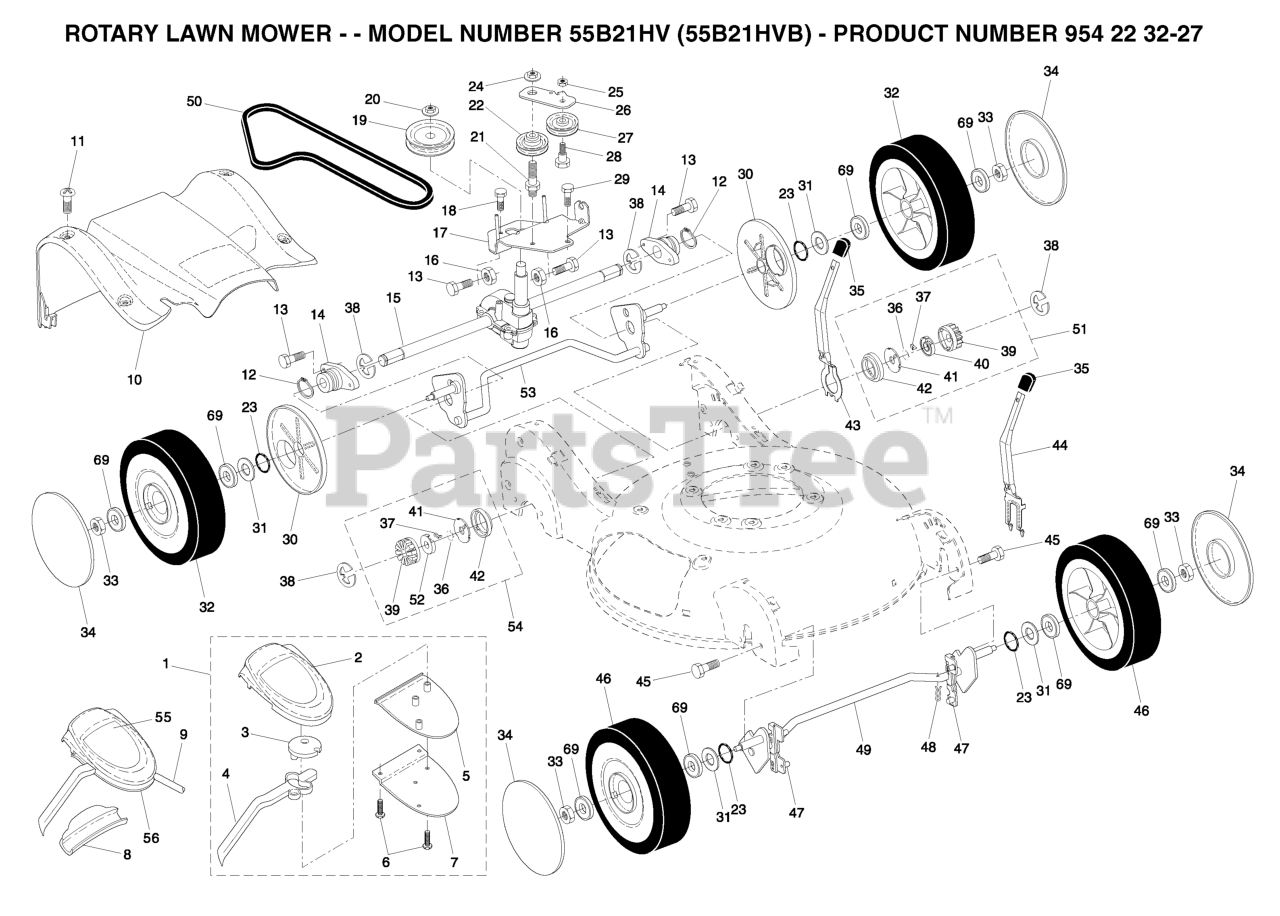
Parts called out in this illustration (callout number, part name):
1	EZ WALK CONTROL
2	COVER, DRIVE CONTROL, TOP
3	PULLEY.CAM.DRIVE.CONTROL.HV
4	LEVER, DRIVE CONTROL
5	COVER, DRIVE CONTROL BOTTOM
6	SCREW, PHILLIPS HEAD 10 X 5/8
7	BRACKET, DRIVE CONTROL
8	EZ WALK SNAP COVER PLATE
9	CABLE, DRIVE CONTROL
10	COVER ASM. DRIVE
11	SCREW
12	RETAINING RING (2 2)(3 2)
13	RP SCREW
14	BEARING.SUPPORT.ASSEM
15	TRANSMISSION.ASM.RGD.EZ.21
16	BEARING.8".WHEEL
17	BRACKET, TRANSMISSION
18	Screw, Hex Washer Head #10-24 x .668
19	PULLEY ASSY
20	NUT
21	BOLT, IDLER
22	RP PULLEY DRIVE
23	O-RING
24	FLANGED LOCKNUT 3/8-16 ZINC
25	NUT.CENTERLOCK.5/16-
26	BRACKET
27	IDLER PULLEY
28	SHOULDER BOLT
29	SCREW 14-20 X 5/8
30	DUST COVER, WHEEL
31	WASHER.FLAT.1/2
32	WHEEL ASM, REAR 9 X 2-1/4
33	HEX FLANGE LOCKNT
34	RB HUBCAP.3-SPOKE.SILVER
35	KNOB.SELECTOR.SPRG.H-GRY (2 2)
36	SPRING, TORSION
37	PAWL.DRIVE.21.EZ-WALK
38	E-RING 7/16 RE
39	GEAR, PINION
40	RETAINER.DRIVE.21.EZ-WALK.LT
41	DISC.DRIVE.21.EZ-WALK
42	SEAL.PINION
43	LEVER, SELECTOR, HEIGHT, REAR
44	LEVER, SELECTOR, HEIGHT, FRONT
46	WHEEL
47	BUSHING.FRONT.TORQUE.SHAFT
48	SPRING RETAINER
49	TORQUE SHAFT ASSY
50	BELT.DRIVE.EZ.WALK.HI-VAC
51	PINION ASSY, LH
52	RETAINER, DRIVE, RH
53	REAR AXLE ASSY.
54	PINION ASSY, RH
69	BEARING.8".WHEEL
